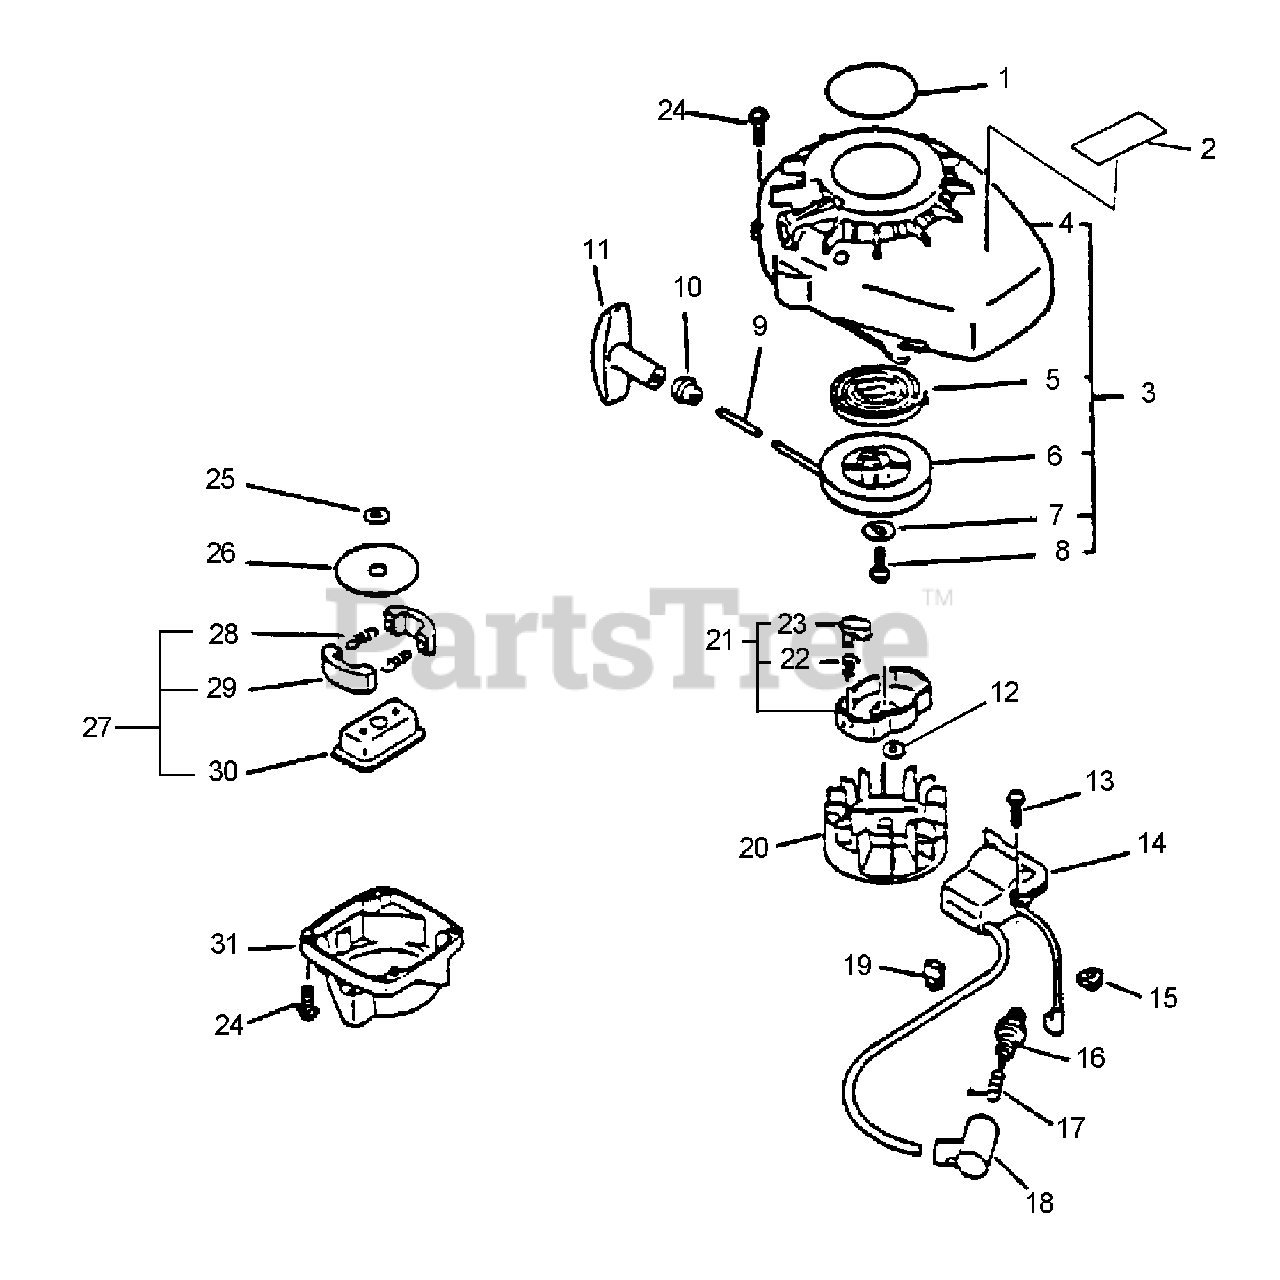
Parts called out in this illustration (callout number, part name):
1	LABEL - MODEL HC-1500
2	LABEL - CAUTION
3	STARTER ASSY
4	COVER, FAN
5	SPRING, REWIND
6	REEL, ROPE
7	WASHER
9	ROPE, STARTER - 3X890
10	GUIDE, ROPE
11	GRIP, STARTER
12	LOCKWASHER - 8
13	SCREW - 4X22
14	COIL, IGNITION
16	SPARK PLUG -- BPM-6A
16	SPARK PLUG -- RCJ-8Y
17	TERMINAL, SPARK PLUG CAP
18	CAP, SPARK PLUG
20	FLYWHEEL
21	STARTER PAWL ASSY
22	SPRING, RETURN
23	PAWL, STARTER - BLACK
24	SCREW - 4X16
25	WASHER, CLUTCH
26	PLATE, CLUTCH
27	CLUTCH ASSY
28	SPRING, CLUTCH
29	SHOE, CLUTCH
30	HUB, CLUTCH
31	CASE, CLUTCH
